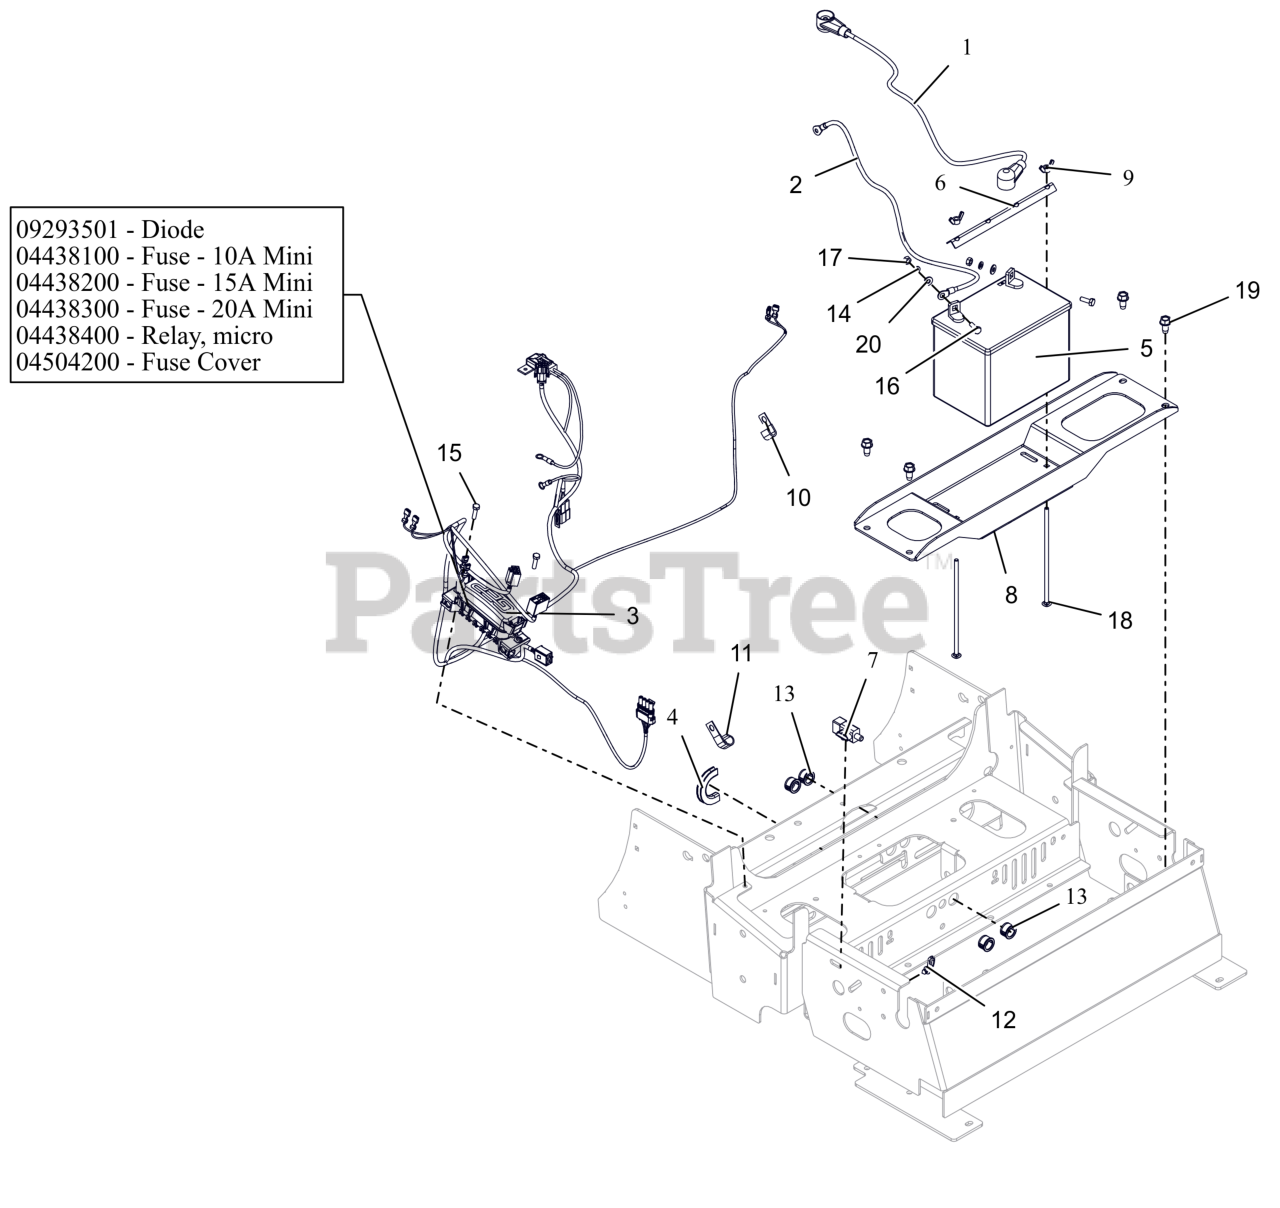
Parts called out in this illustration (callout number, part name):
1	CABLE - POS BATT W/BOOTS 6X35
2	CABLE-NEGATIVE BATTERY 35.00"
3	DIODE, CONNECTOR SHELL
3	FUSE,10 AMP MINI-ATC
3	FUSE,15 AMP MINI-ATC
3	FUSE,20 AMP MINI ATC
3	RELAY,MICRO5 TERML W/RESISTOR
3	COVER, HARNESS FUSE/RELAY MOD
3	HRNSS,PT200/400 NON-EFI WIRING
4	STRIP, COWL
5	BATTERY, 300 CCA 10U1L
6	HOLD DOWN
7	SWITCH, SNAP IN - N.O./N.O.
8	PT200/400 BATTERY TRAY - RED
9	NUT, LK-WING .25-20 ZCC
12	CABLE TIE W/ TREE (.25 HOLE)
13	BUSH, PANEL SNAP .687X.875X.56
14	WSHR,LK-REG .250X.062 ZCC
15	BLT, HEX M6-1.0 X 25 G8.8 ZCC
16	BLT, HEX .25-20X.75 G5 ZCC
17	NUT-STD .250-20 G2 ZCC
18	BTL,RHSN .250-20 X 7.5 G5 ZCC
19	SCR,TAP .375-16X.75 HWH TR ZCC
20	WSHR,FLT .281X.625X.065 ZCC
